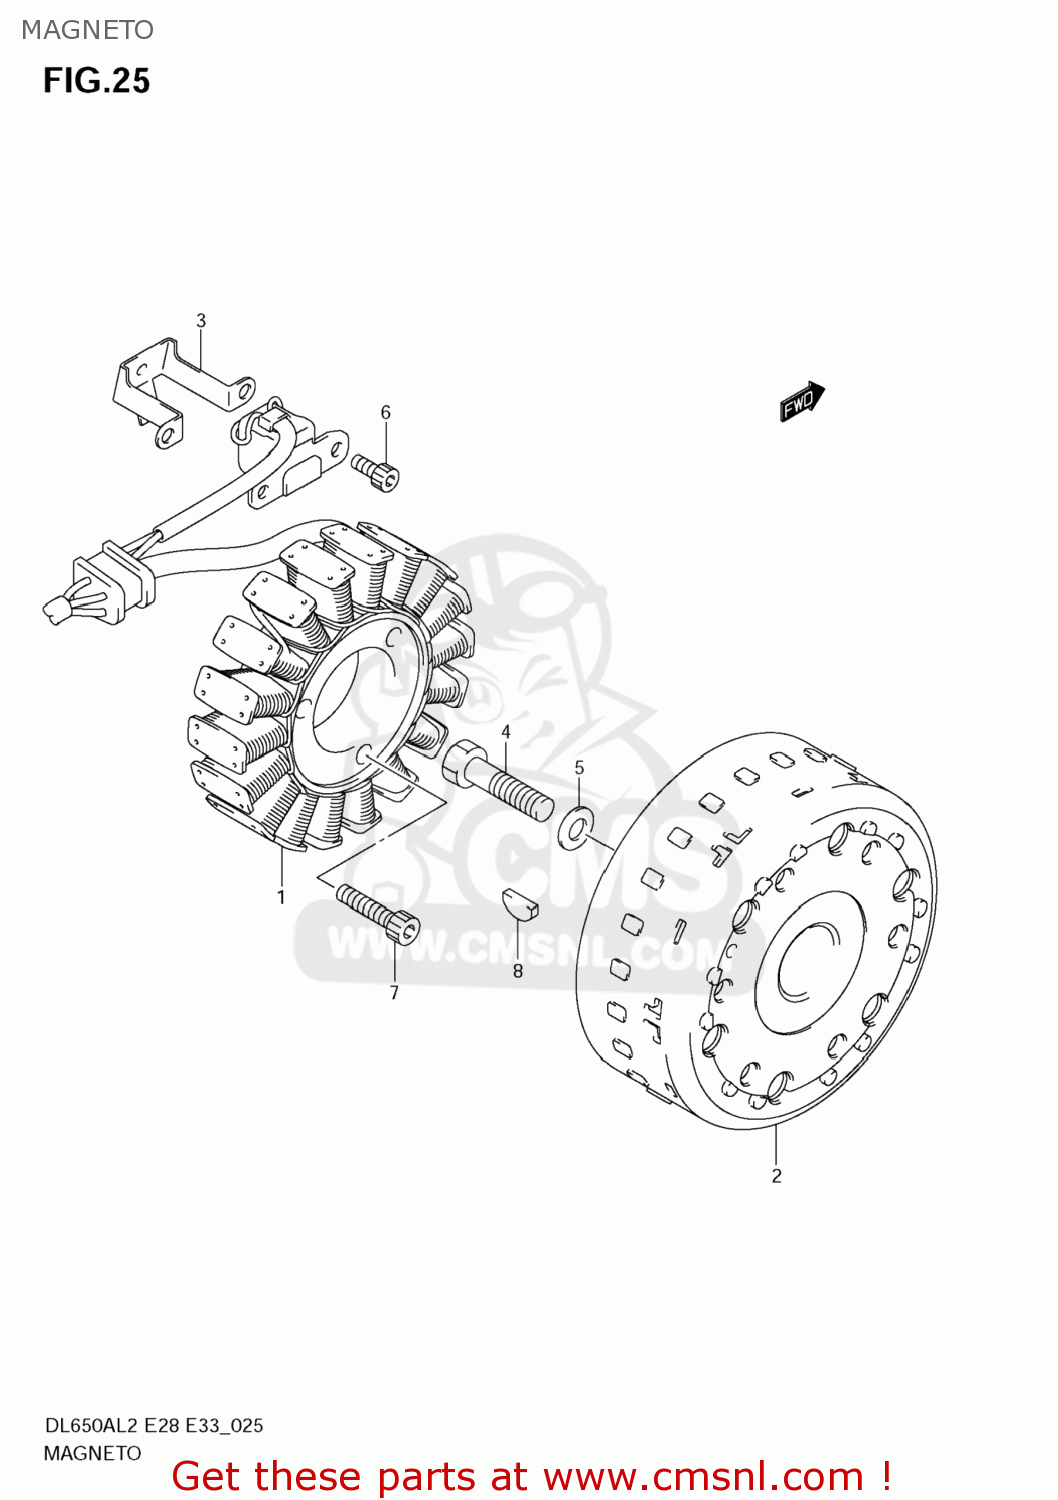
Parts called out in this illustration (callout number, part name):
1	STARTER ASSY
2	ROTOR ASSY
3	CLAMP,MAGNETO LEAD
4	BOLT(12X40)
5	WASHER(12X30X3)
6	BOLT
7	BOLT
8	KEY
